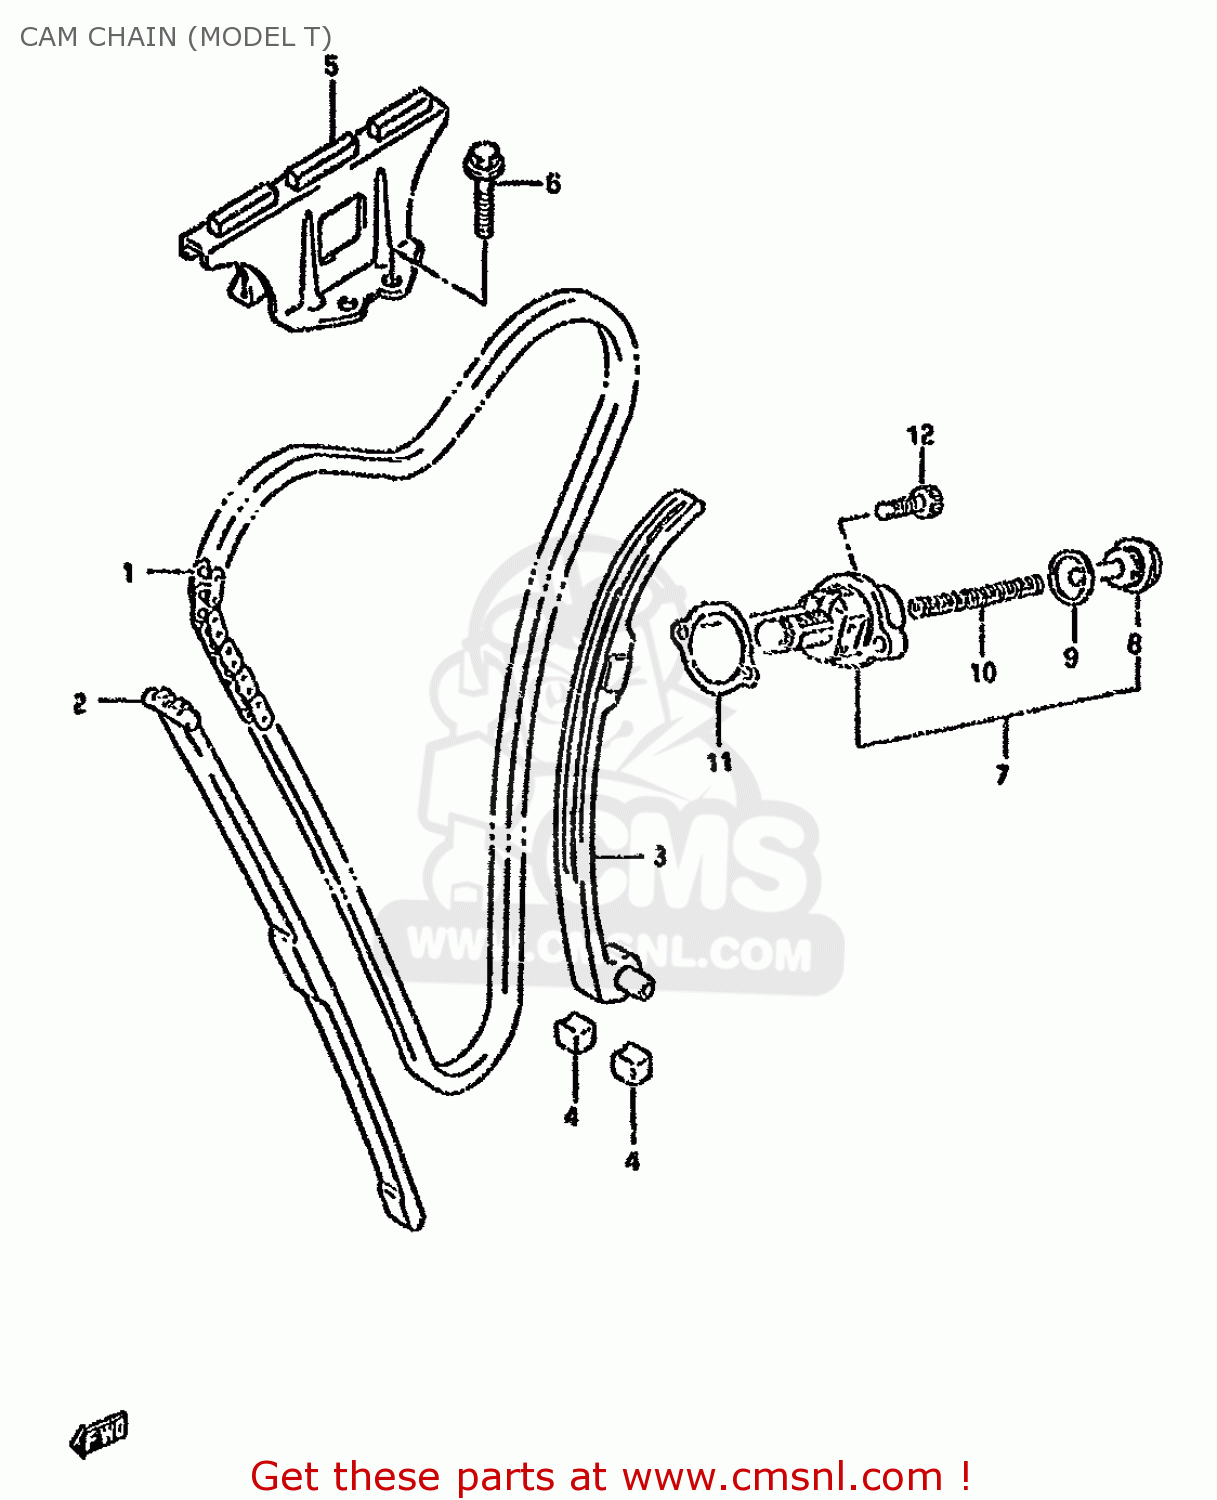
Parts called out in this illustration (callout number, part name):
1	CHAIN,CAMSHAFT DRIVE
2	GUIDE,CAM CHAIN NO.1
3	TENSIONER,CAM CHAIN
4	CUSHION,CAM CHAIN TENSIONER
5	GUIDE,CAM CHAIN NO.2
6	BOLT
7	ADJUSTER ASSY,TENSIONER
8	PLUG
9	GASKET (NAS)
10	BOLT
11	GASKET(5.8X13X1.2) (NAS)
12	BOLT,CL.COVER
13	PLUG
14	GASKET (NAS)
15	SPRING
16	GASKET,TENSIONER ADJUSTER (NAS)
17	BOLT
